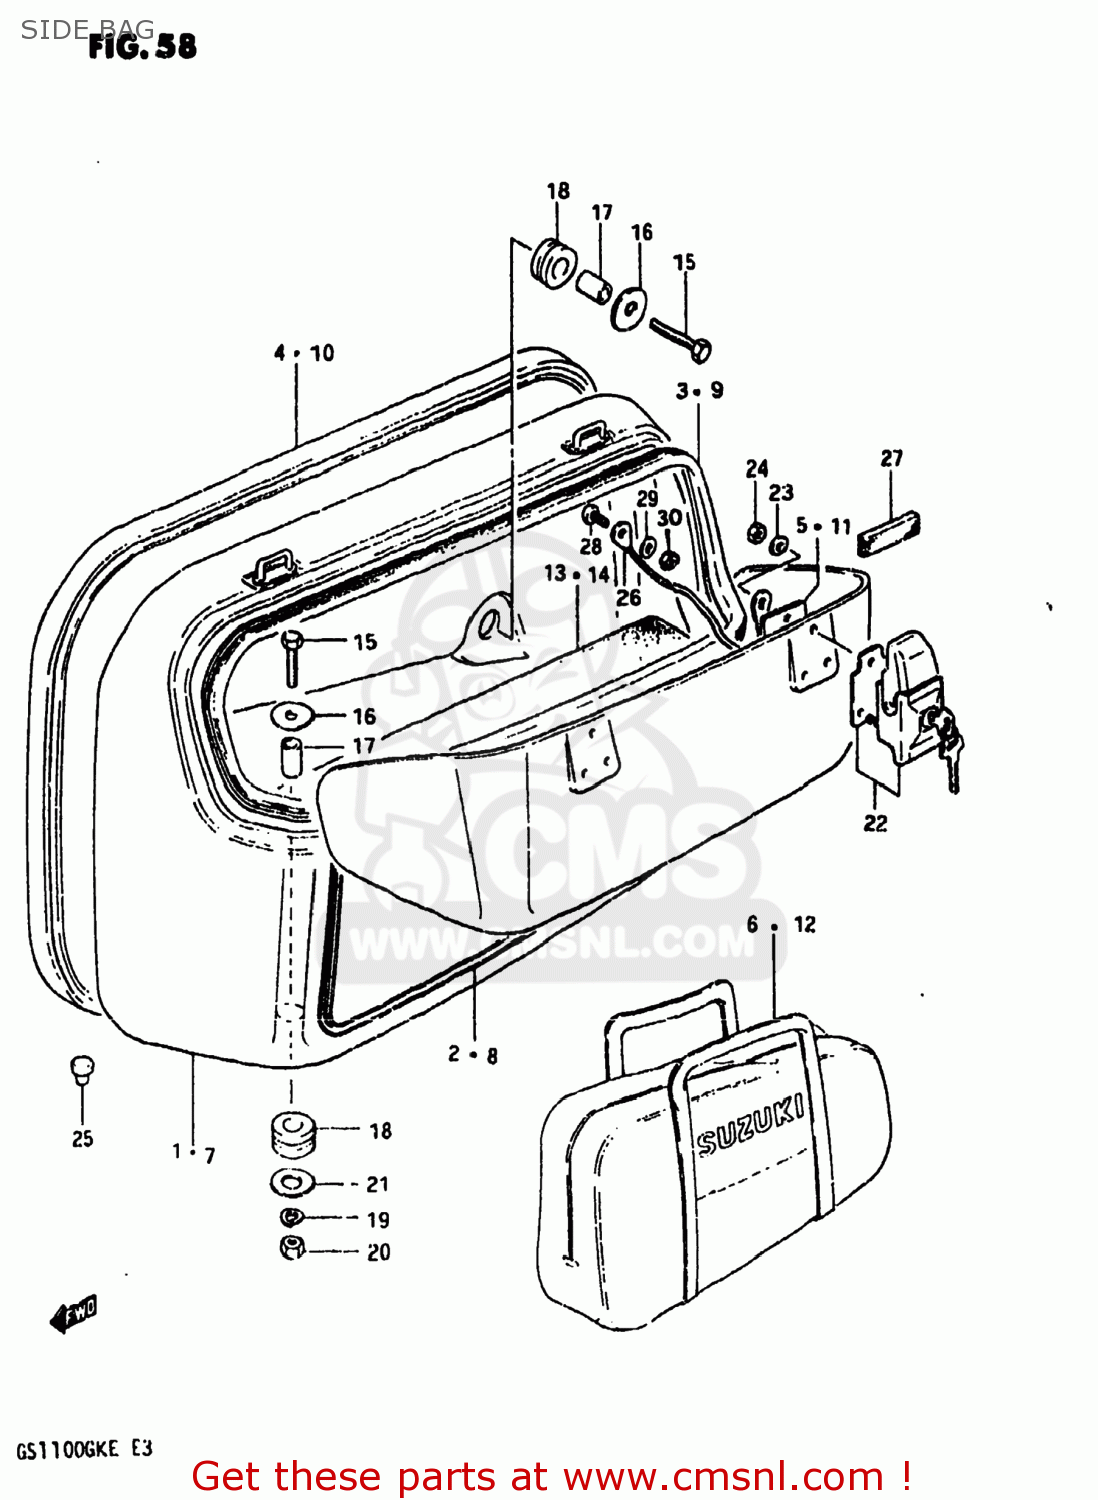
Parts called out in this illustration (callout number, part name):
1	SIDE BAG ASSEMBLY,RIGHT
2	TAPE SET,SIDE BAG,RIGHT
3	SEAL,TRAVEL TRUNK
4	MOLDING,SIDE BAG
6	LUGGAGE BAG RH
7	SIDE BAG ASSEMBLY,LEFT
8	TAPE SET,SIDE BAG,LEFT
9	SEAL,TRAVEL TRUNK
10	MOLDING,SIDE BAG
12	LUGGAGE BAG LH
13	CUSHION
14	CUSHION
15	BOLT
16	WASHER (6.5X29X1.6)
17	SPACER
18	CUSHION
19	LOCK WASHER
20	NUT
21	WASHER (6.5X20X1.2)
22	LOCK,TRANK LID
23	WASHER
24	NUT
25	PLUG(OD:14)
28	SCREW
29	WASHER
30	NUT
